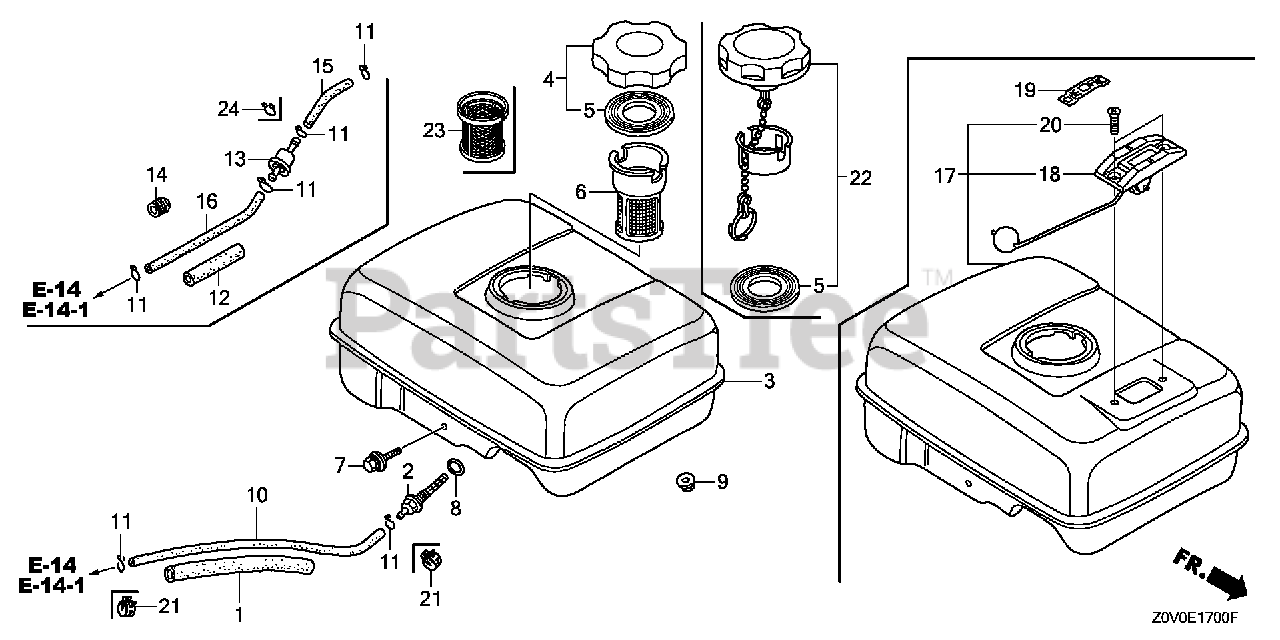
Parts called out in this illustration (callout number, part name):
1	RUBBER, SUPPORTER (107MM)
10	BULK HOSE, FUEL (4.5X3000) (4.5X140)
11	CLIP, TUBE (B8)
